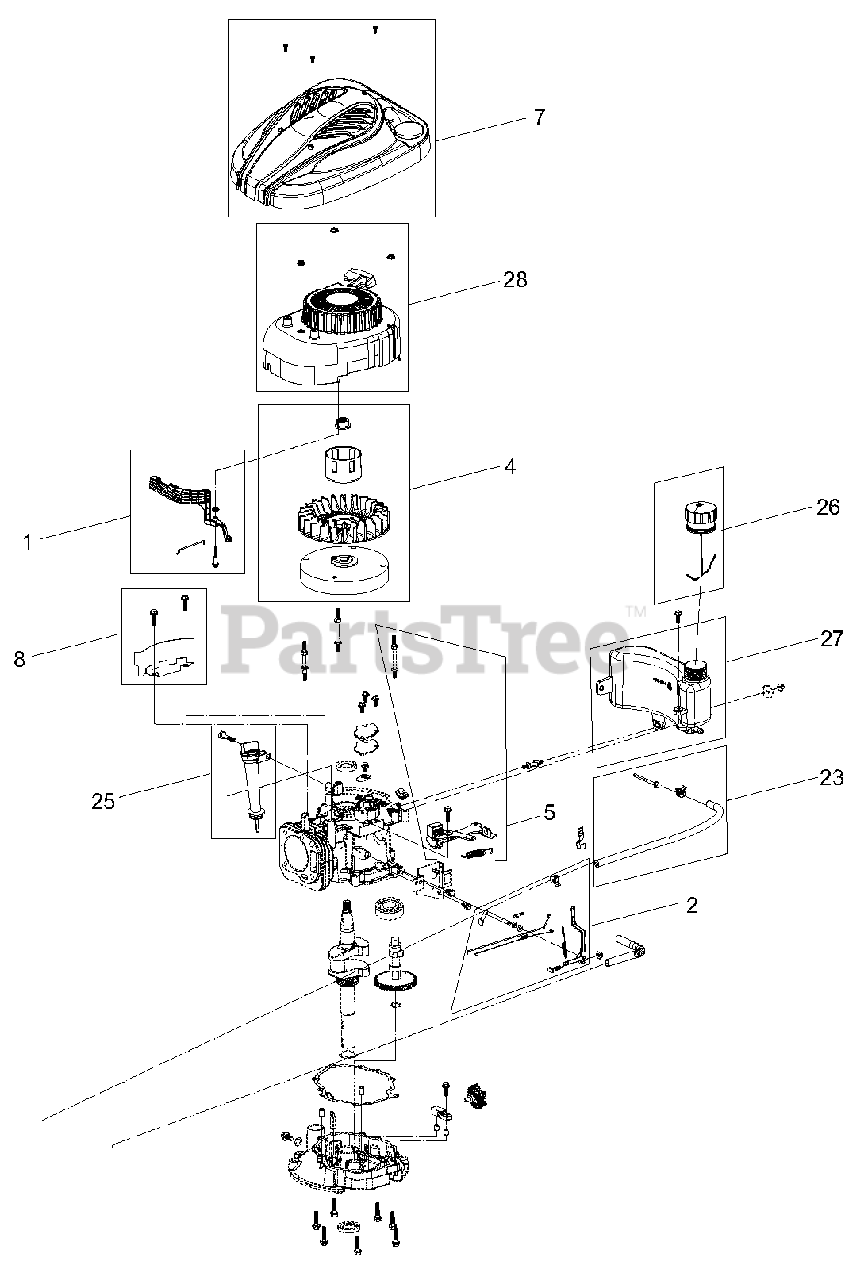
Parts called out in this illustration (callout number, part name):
1	AIR VANE CHOKE KIT
2	GOVERNOR ARM KIT
3	MUFFLER AND SHIELD KIT
4	FLYWHEEL AND FAN KIT – RECOIL START
5	KIT BRAKE ASSEMBLY RECOIL
7	KIT ARIENS STYLE
8	KIT FLYWHEEL SHIELD
9	THERMAL CHOKE CONTROL KIT
10	KIT-AIR CLEANER ASM, 2 HINGE
11	CARBURETOR COMPLETE KIT
12	IGNITION COIL KIT
18	KIT-VALVE COVER (1P65FA)
19	LOCK-THROTTLE
20	STUD-INTAKE
21	AIR FILTER, FOAM PRE-FILTER
22	AIR FILTER ELEMENT
23	FUEL LINE WITH STRAINER
24	SPARK PLUG
25	OIL FILTER TUBE/CAP
26	GAS CAP WITH CANISTER
27	FUEL TANK
28	RECOIL ASSEMBLY
